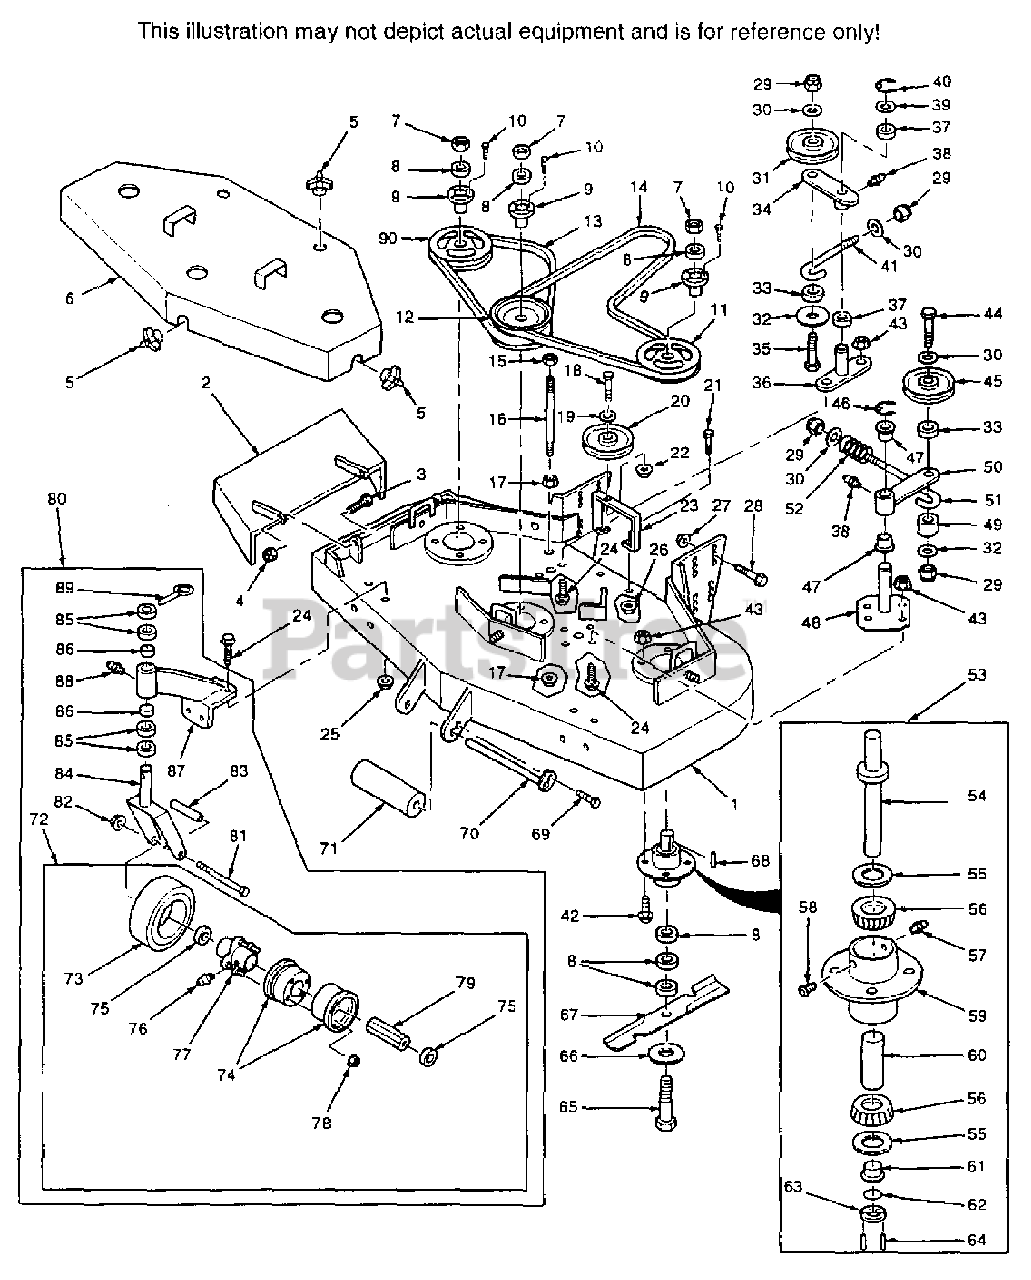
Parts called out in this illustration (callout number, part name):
5	WING NUT, 3/8-16 X 7/8
7	HEX NUT, 5/8-11
8	SPACER, CUTTER BLADE
9	TAPERED HUB
16	STUD, 3/8-16 X 6 3/4
17	SERR. FL. HEX NUT, 3/8-16
24	SERR. FL. HH CPSCR, 5/16-18 X 3/4
25	SERR. FL. HEX NUT, 5/16-18
27	SERR. FL. HEX NUT, 1/2-13
28	SERR. FL. HH CPSCR, 1/2-13 X 1-1/4
31	IDLER PULLEY
33	SPACER
34	IDLER ARM(INCLUDES ITEMS 37 AND 38)
36	IDLER PIVOT
37	BEARING, BRONZE OILITE
38	GREASE FITTING, STR 1/4-28 SELF TAP
39	FLATWASHER, 3/4
40	RETAINING RING
41	J-ROD, IDLER PULLEY
42	SERR. FL. HH CPSCR, 5/16-18 X 1-1/4
43	SERR. FL. HEX NUT, 5/16-18
45	PULLEY ASSEMBLY
46	RETAINING RING
47	BEARING, BRONZE OILITE
48	IDLER PIVOT SUPPORT
49	SPACER
50	IDLER ARM(INCLUDES ITEMS 38 AND 47)
51	J-ROD
52	SPRING, CUTTER DECK
53	SPINDLE ASSEMBLY TAPERED BEARING
54	SPINDLE SHAFT, TAPERED BEARING
55	SEAL, TAPERED BEARING SPINDLE
56	TAPERED BEARING
57	GREASE FITTING, STR. 5/16 SERR.
58	RELIEF FITTING, CUTTER SPINDLE
59	SPINDLE HOUSING, TAPERED BEARING
60	SLEEVE, CUTTER SPINDLE
61	SPINDLE BUSHING
62	RETAINING RING, 1" EXT.-INVERTED
63	SPACER, CUTTER BLADE
65	BOLT, HEX HEAD 5/8-11 X 9-1/2
66	FLATWASHER, 5/8
68	KEY, 1/4 X 1/4 X 2
69	SERR. FL. HH CPSCR, 5/16-18 X 1/2
70	ROLLER SHAFT
71	GUIDE ROLLER
72	WHEEL ASSEMBLY
73	TIRE ONLY, CASTER WHEEL
73	INNER TUBE ONLY, CASTER WHEEL
74	RIM PAIR, CASTER WHEEL
75	RETAINER, CASTER WHEEL
76	GREASE FITTING, 45 DEGREE 1/4-28
77	HUB ASSEMBLY W/BOLTS, CASTER WHEEL
78	TAPERED HEX NUT, 5/16-18
79	ROLLER BEARING, CASTER WHEEL
80	CASTER WHEEL ASSEMBLY
83	SLEEVE, CASTER WHEEL BEARING
84	CASTER YOKE
85	SPACER, CASTER YOKE, 1/2" LONG
86	BRONZE BEARING
87	SUPPORT ASSEMBLY(INCLUDES ITEMS 88-90)
88	GREASE FITTING, STR. 1/4-28
89	QUICK PIN
90	PULLEY
